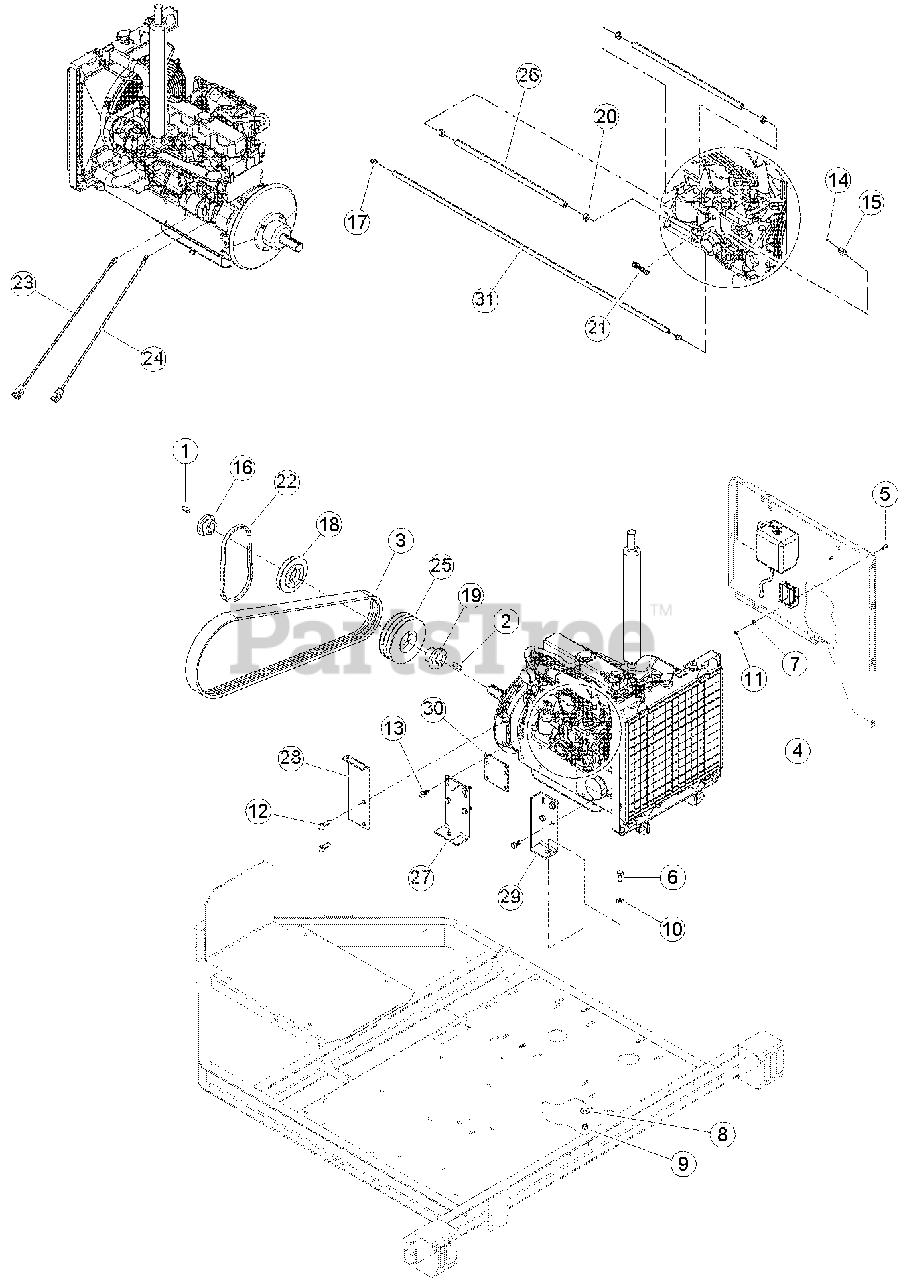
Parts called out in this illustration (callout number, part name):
1	KEY, 3/8 SQUARE X 1-1/4 LONG
2	KEY, 3/8 SQUARE X 1-3/4 LONG
3	BELT, 3B90 BANDED
4	ENGINE, KUBOTA DIESEL 2.2L (FOR SERVICE SEE ENGINE OWNER'S MANUAL OR YOUR NEAREST AUTHORIZED INDUSTRIAL KUBOTA ENGINE DEALER.)
5	BOLT, 1/4 X 3/4 HEX HD GR5 ZP
6	BOLT, 1/2 X 1-1/4 HEX HD GR5 ZP
7	WASHER, 1/4 FLAT ZP
8	WASHER, 1/2 FLAT ZP
9	NUT, 1/2 CENTERLOCK GRB ZP
10	WASHER, 1/2 SAE FLAT ZP
11	NUT, 1/4 NE NYLOCK ZP
12	BOLT, M14-1.5 X 20 HEX HD GR8.8 ZP
13	BOLT, M12-1.25 X 25 HEX HD GR8.8 ZP
14	SCREW, #8-32 X 3/16 KNR CUP PT
15	PIN, 1/4 BOWDEN
16	BUSHING, SDS 1-7/16
17	CLAMP, 15/32 SPRING
18	SHEAVE, 1B5.2 SDS
19	BUSHING, SD 1-7/16
20	CLAMP, 9/16 SPRING
21	BULKHEAD FITTING
22	BELT, BX30
23	CABLE, 72 IN. POSITIVE BATTERY
24	CABLE, 72 IN. NEGATIVE BATTERY
25	SHEAVE, 3B6.8 SD
26	HOSE, 15 IN. FUEL LINE
27	WELDMENT, ENGINE MOUNT
28	ANGLE, SPRING ANCHOR
29	WELDMENT, FRONT ENGINE MOUNT
30	PLATE, MOUNT SPACER
31	HOSE, 38 IN. FUEL LINE
